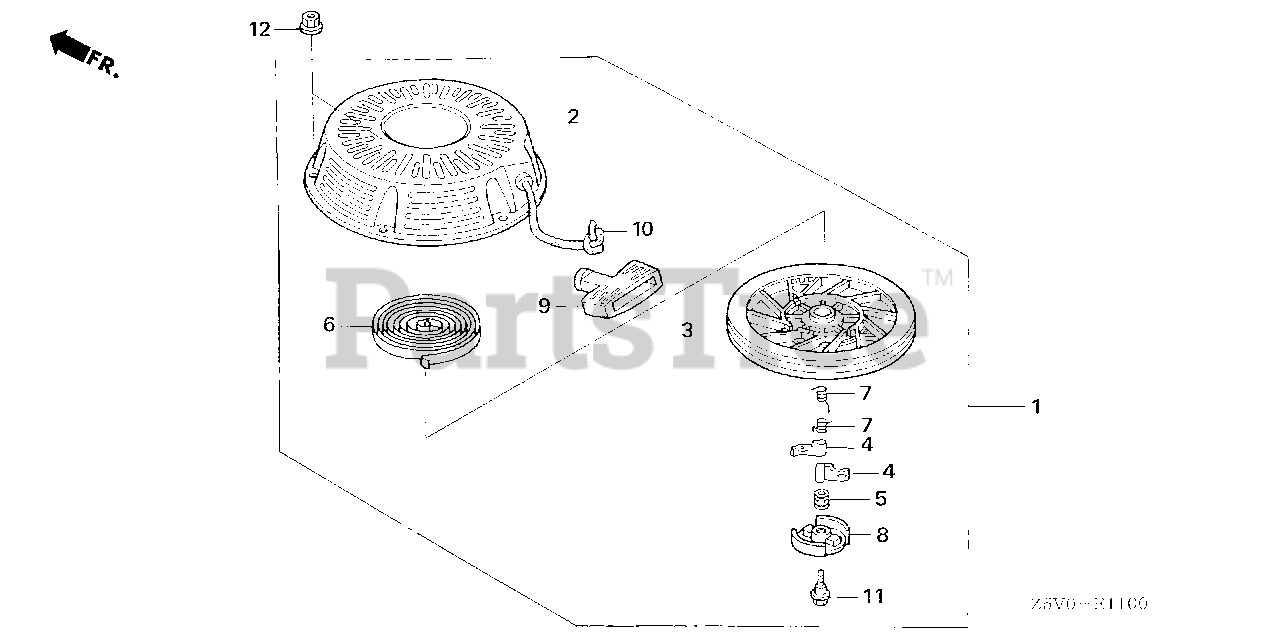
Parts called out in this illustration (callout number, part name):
1	STARTER ASSY., RECOIL *R280* (POWER RED)
2	CASE, RECOIL STARTER *R280* (POWER RED)
3	PULLEY, RECOIL STARTER
4	RATCHET, STARTER
5	SPRING, FRICTION
6	SPRING, STARTER RETURN
7	SPRING, RATCHET
8	RETAINER, SPRING
9	GRIP, STARTER
10	ROPE, RECOIL STARTER
11	SCREW, CENTER
12	NUT, FLANGE (6MM)
